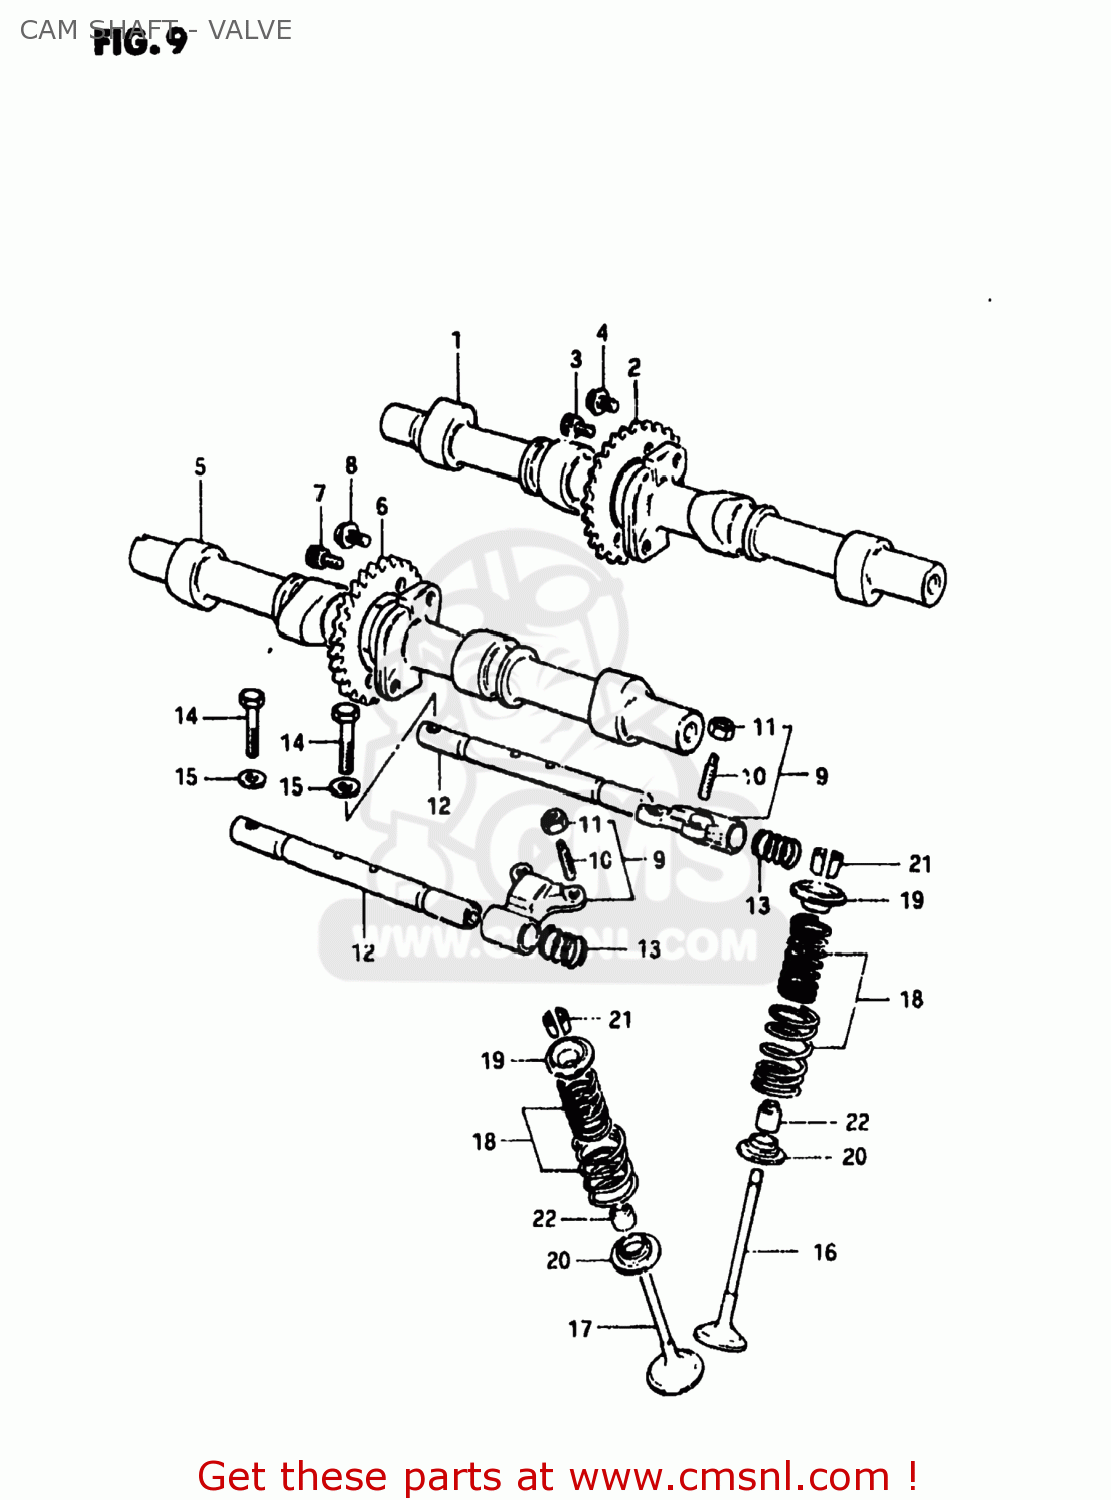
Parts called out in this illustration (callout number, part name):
1	CAMSHAFT
2	SPROCKET,CAMSHAFT
3	BOLT 6X11
4	BOLT(7X11)
5	CAMSHAFT,EXHAUST
6	SPROCKET,EXHAUST CAMSHAFT
7	BOLT 6X11
8	BOLT(7X11)
9	ARM,VALVE ROCKER
10	SCREW,TAPPET ADJUSTING
11	NUT,ADJUSTING
12	SHAFT,VALVE ROCKER
13	SPRING
14	BOLT
15	WASHER
16	VALVE,INTAKE
17	VALVE,EXHAUST
18	SHIM,TAPPET
19	RETAINER,VALVE SPRING
20	SEAT,VALVE SPRING
21	COTTER VALVE
22	OIL SEAL
